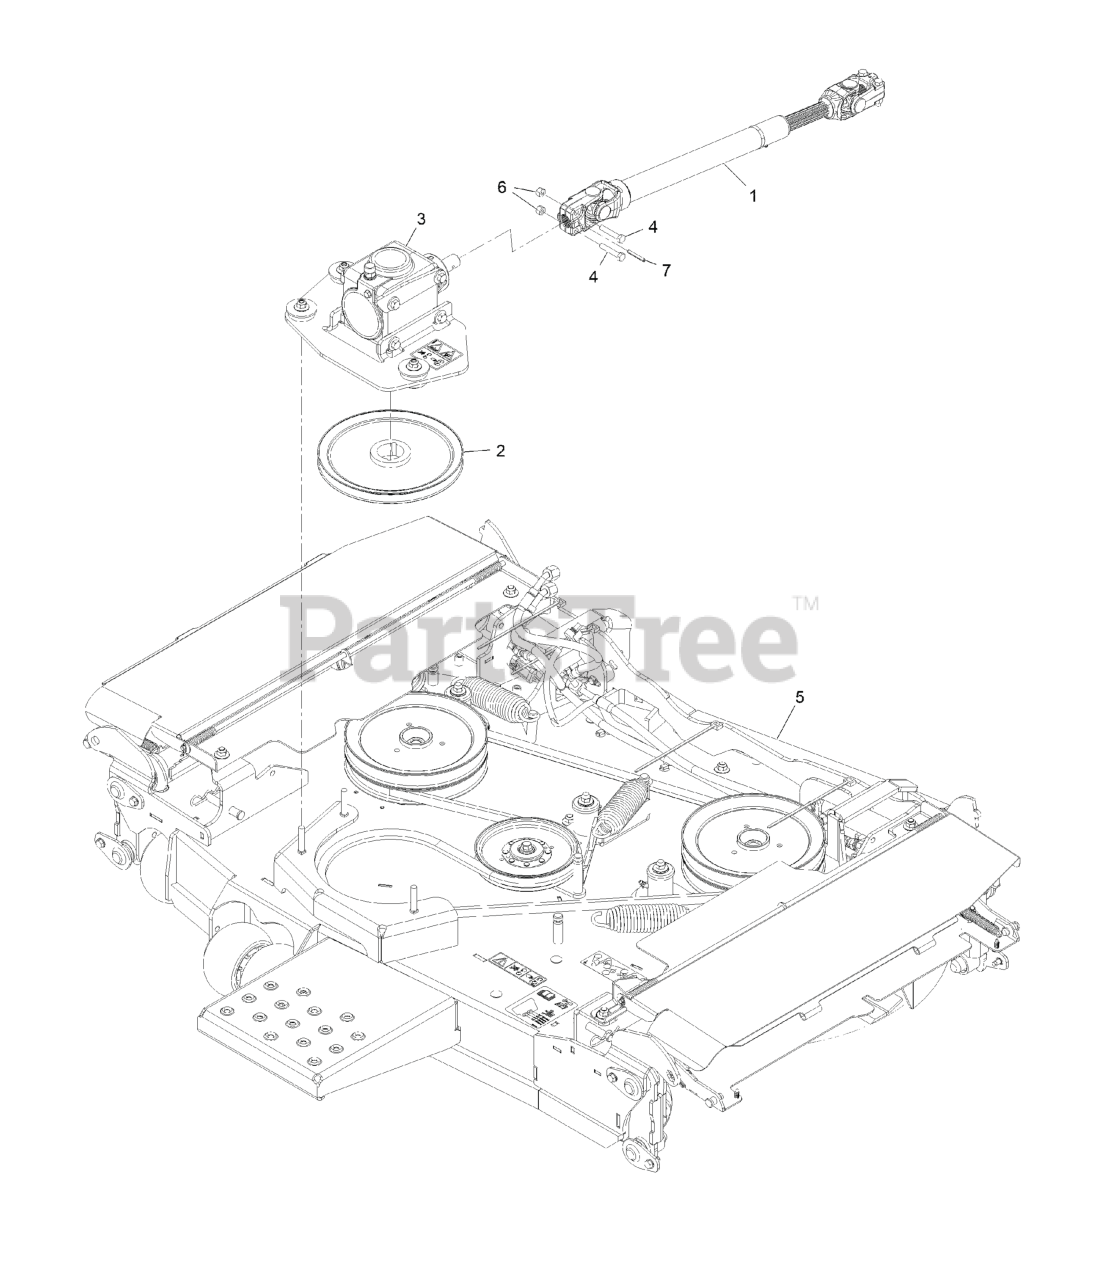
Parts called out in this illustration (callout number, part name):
1	DRIVESHAFT ASM
3	Gearbox ASM
4	SCREW-HH
6	NUT-LOCK, NI
7	PIN-ROLL
